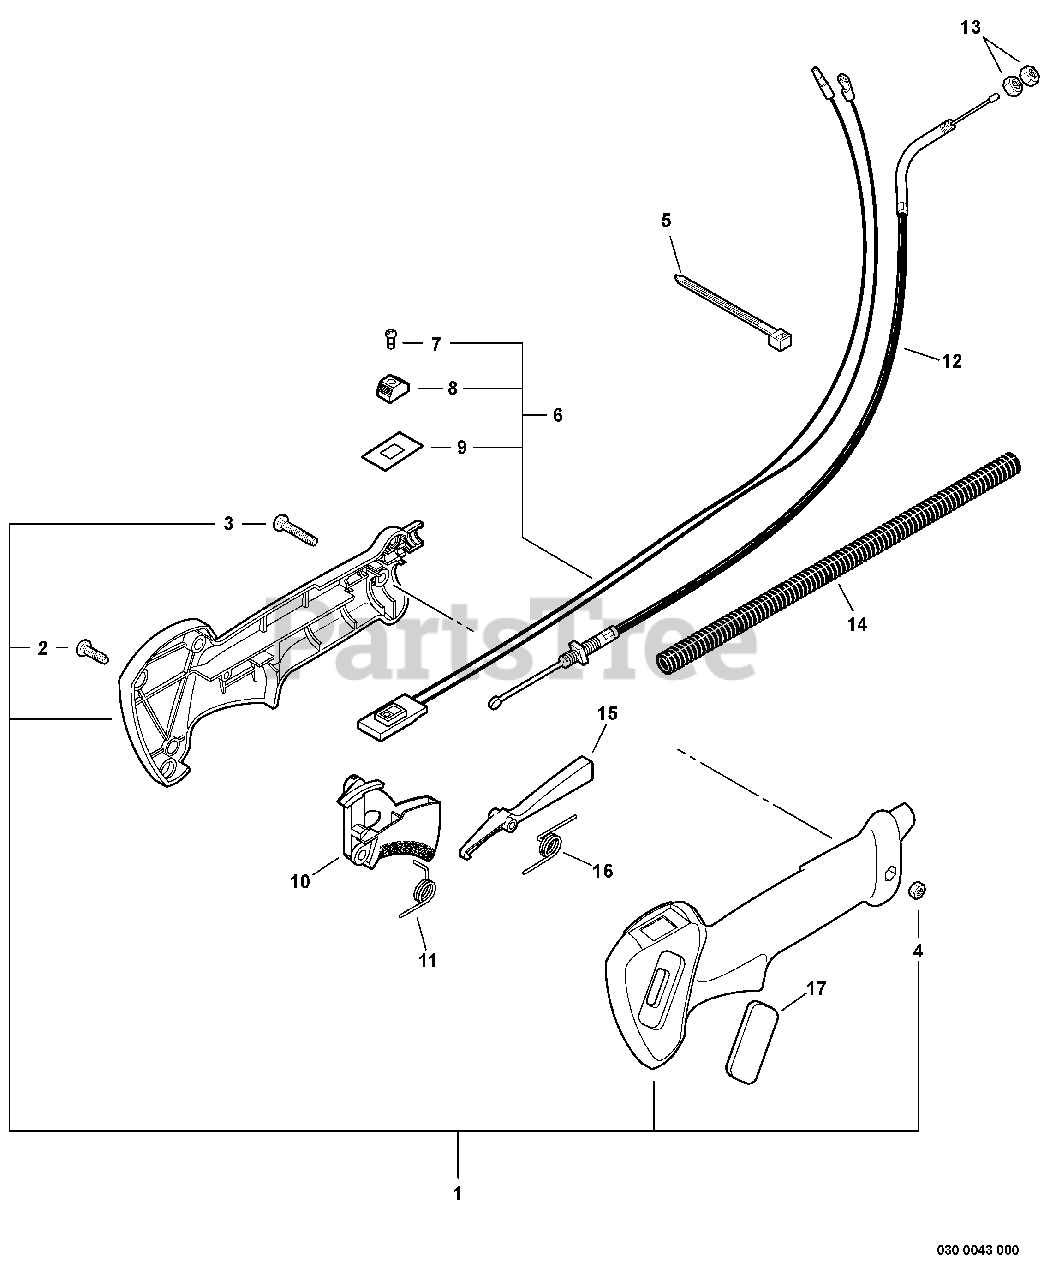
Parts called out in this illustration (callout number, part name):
1	CONTROL HANDLE ASSY
2	SCREW - 4X16
3	SCREW - 5X30
5	TIE, CABLE
6	IGNITION SWITCH KIT
7	SCREW - 3X10
8	KNOB, SWITCH - ORANGE
9	COVER, SWITCH - STOP
10	TRIGGER, THROTTLE
11	SPRING, TRIGGER
12	CABLE, THROTTLE
14	TUBE, PROTECTIVE - CORRUGATED
15	LEVER, TRIGGER LOCKOUT
16	SPRING, LOCKOUT LEVER
